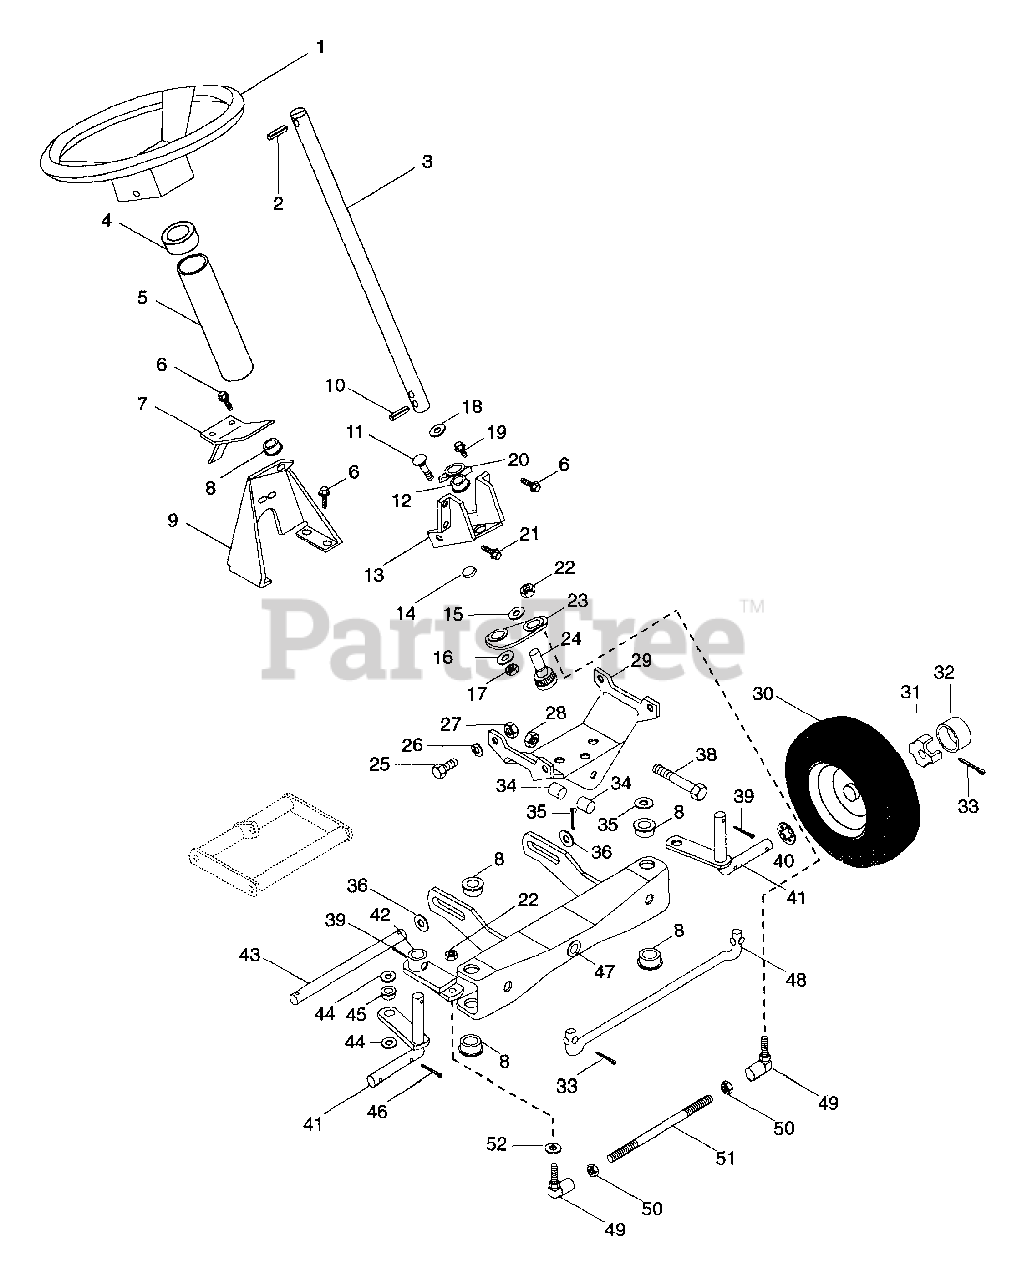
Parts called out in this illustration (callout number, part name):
1	STEERING WHEEL 13"
2	PIN-ROLL .250X1.75
3	STEERING SHAFT
5	TUBE 1.865 X 2.00 X 11.33
6	SCR-TAP .312-18X.50 HWH PL TR
8	FLANGE BUSHING
9	STEERING SUPPORT
10	PIN-ROLL .188X1.00
11	BLT-RDHDSQSHNK .38-16X1.00 PL
12	BSHG-FLG .625X1.156X.375 SI
13	STEERING BRACKET
14	SPACER .380X.750X.236
15	WSHR-FL-STL .630X1.250X.062 PL
16	WSHR-FL-STL .390X1.500X.125
17	NUT-LK-JAM-CTR .375-16 PL
18	WSHR-HDND-STL-THR.515X.97X.062
19	SCR-TAP 10-24X.25 CRSLPH PL 1A
20	RETAINING PLATE
21	SCR-TAP .312-18X.50 PL F
22	NUT-LK .375-24 PL
23	STEERING GEAR
24	PINION
25	BLT-SERRDHD SL .31-18X.75 YZ
26	WSHR-LK .375X.094 MED PL
27	NUT-FLG. .312-18 PL
28	NUT-LK-CTR .50-13
29	AXLE BRACKET
30	T/WHL ASSY
30	TIRE 4.10/3.50-4
30	ZERK FITTING
30	BSHG-FLG .750X1.380X.750X1.557
30	WHL-COMP
31	SPINDLE CUP
32	HUB CAP
33	PIN-COTR .12X1.0 PL
34	BSHG-SLV .500X.750X1.560
35	PIN-COTR .09X.75 PL
36	WSHR-FL-STL .505X.880X.072 PL
37	WSHR-FL-STL .755X1.375X.062 PL
38	BLT-HEX .50-13X4.00 PL GR2
39	PIN-GRV .250X1.25 TP A
40	SPINDLE WASHER
41	R.H. WHEEL SPINDLE
41	L.H. WHEEL SPINDLE
43	HANGER PIN
44	WSHR-FL-STL .505X.875X.024 PL
45	BSHG-FLG.500X.625X.312X.750NY
46	PIN-COTR .12 X 1.25 PL
48	TIE ROD
49	BALL JOINT
50	NUT .375-24 PL
51	STEERING LINK
52	WSHR-FL-STL.406X.812X.065PL
